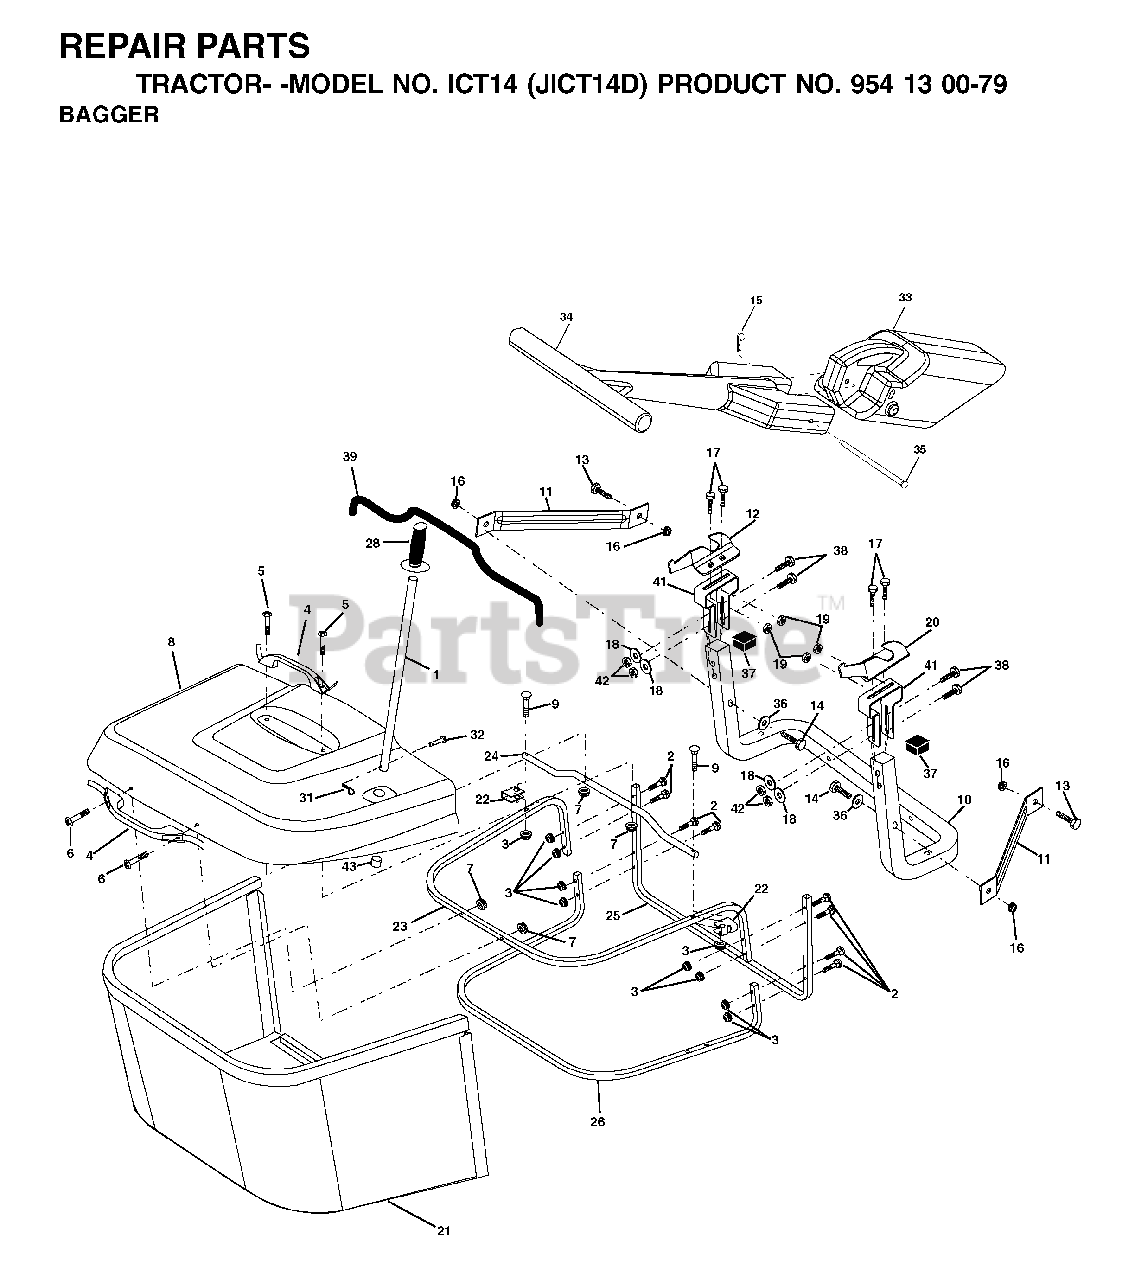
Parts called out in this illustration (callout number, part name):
1	TUBE HANDLE
3	NUT T
5	SCREW.PAN.HEAD
11	BRACKET
14	BOLT-HEX EAK
15	RETAINER-SPRNG RB
16	NUT LOCK FLG 3/8-16 UNC
17	BOLT
18	WASHER M
19	NUT LOCK HEX FLANGE 5/16-18
20	BRACKET
21	GRASS BAG
22	BRACKET
23	TUBE
24	TUBE
26	TUBE
28	GRIP.HANDLE.BLACK
31	RETAINER M
32	RIVET,DRILLED
33	PLUG
35	PIN
36	WASHER
38	BOLT.5/16-18X2.5
41	BRKT, BAGGER
42	NUT.71038.31-18.HEX.NYLOCK
43	PLUG, TUBING END
